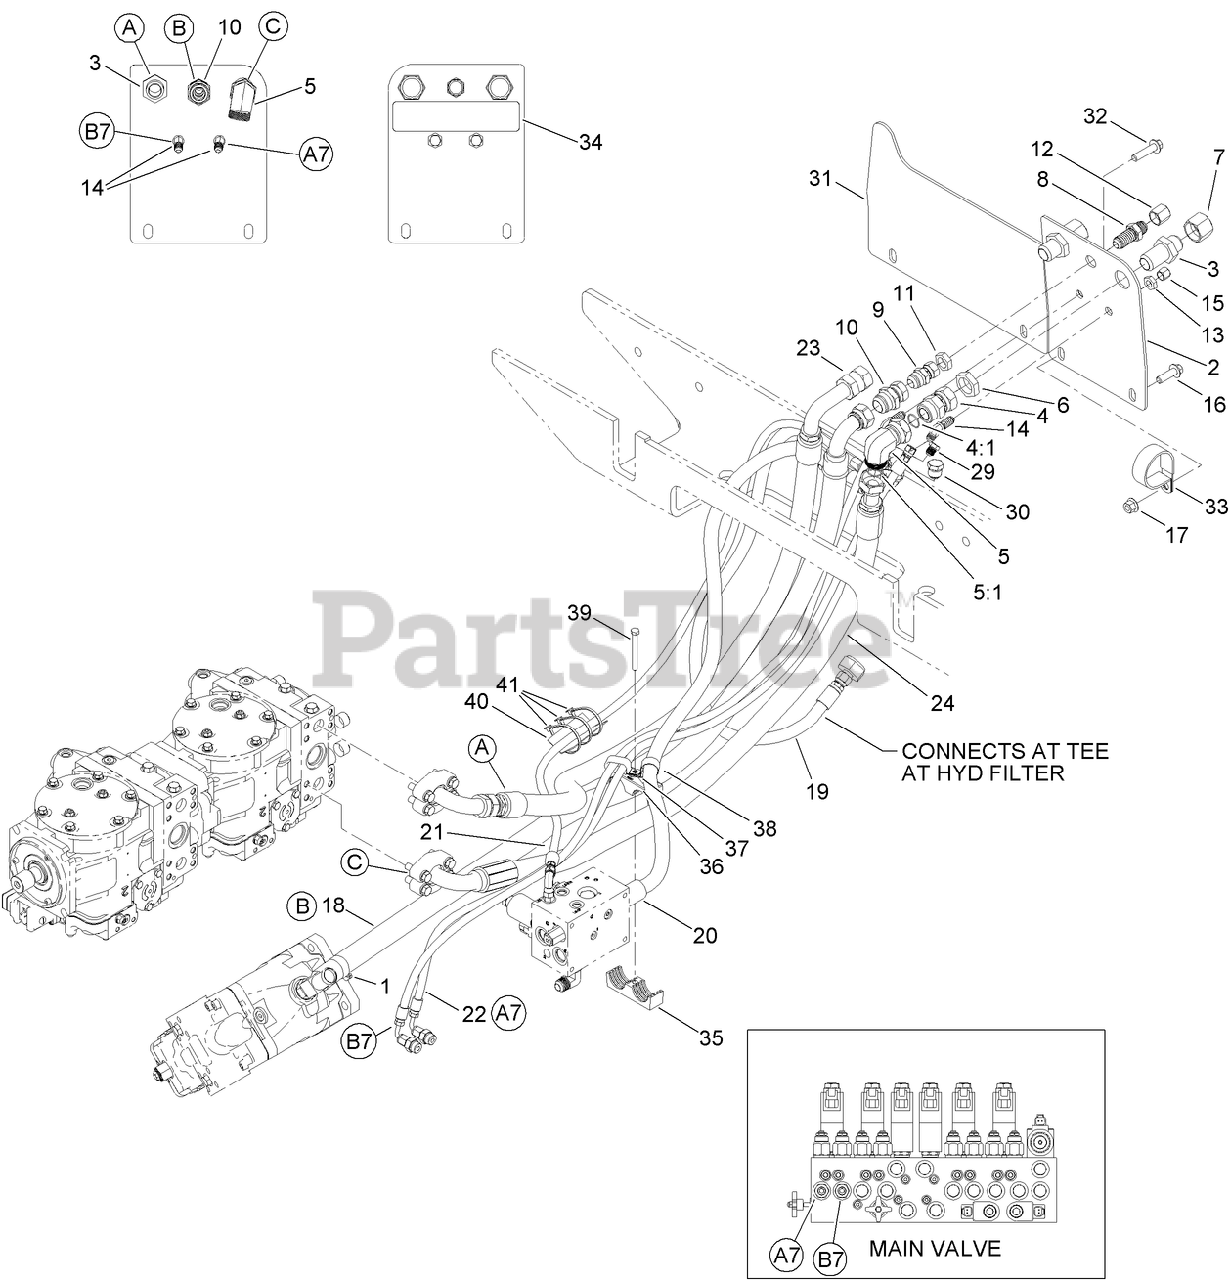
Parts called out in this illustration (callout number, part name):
1	CLAMP-HOSE
2	PLATE-MOUNTING, HYD FITTINGS
3	UNION-BULKHEAD
4	FITTING-STRAIGHT
4:1	O-RING
5	FITTING-SWIVEL, 90 DEG
5:1	O-RING
6	NUT-LOCK, BULKHEAD
8	UNION-BULKHEAD
9	ADAPTER-REDUCER
10	ADAPTER-REDUCER
11	NUT-LOCK, BULKHEAD
12	FITTING-CAP
13	NUT-LOCK, BULKHEAD
14	FITTING-BULKHEAD, ELBOW 45
16	SCREW-HHF
17	NUT-LOCK, HHF
18	HYD RETURN HOSE ASM
19	HYD HOSE ASM, HP
20	HYD HOSE ASM, HP
21	HYD HOSE ASM, HP
22	HYD HOSE ASM, HP
23	HYD HOSE ASM, HP
24	HYD HOSE ASM
31	PLATE-COVER
32	SCREW-HHF
33	CLAMP-R
34	DECAL-ATTACHMENT CONNECTION
35	CLAMP-TWIN
36	PLATE-REATAINER, CLAMP
38	R-CLAMP
39	SCREW-HH
40	PROTECTOR-HOSE
41	TIE-CABLE
